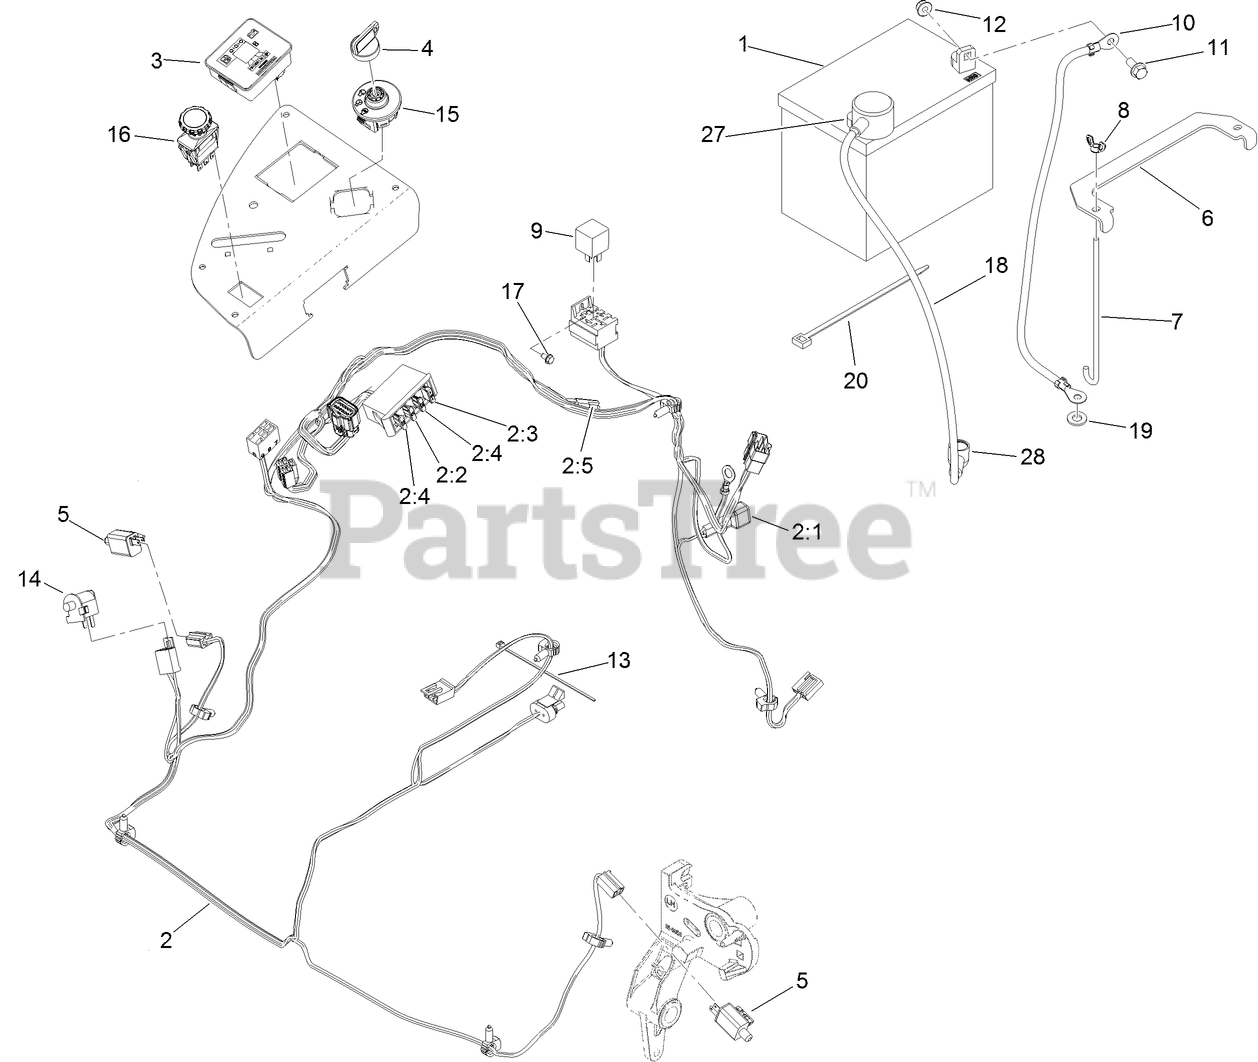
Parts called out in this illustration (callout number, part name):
1	BATTERY-DRY
2	HARNESS-WIRE, MAIN
2:2	FUSE-BLADE, 10 AMP
2:3	FUSE-BLADE, 15 AMP
2:4	FUSE-BLADE, 25 AMP
2:5	CAP-PLUG
3	FUEL/HOUR METER ASM
4	KEY-IGNITION
5	SWITCH
6	STRAP-TIE DOWN, BATTERY
7	BOLT-HOLDDOWN
8	WINGNUT
10	CABLE-BATTERY, NEGATIVE
11	SCREW-HHF
12	NUT-HF, NI
13	TIE-CABLE
14	SWITCH-BAIL
15	SWITCH-IGNITION
16	SWITCH-PTO, 10 AMP
17	SCREW-HWH
18	CABLE-BATTERY, POSITIVE
19	WASHER-FLAT
20	TIE-PLASTIC
27	INSULATOR-BATTERY
28	INSULATOR-SOLENOID
